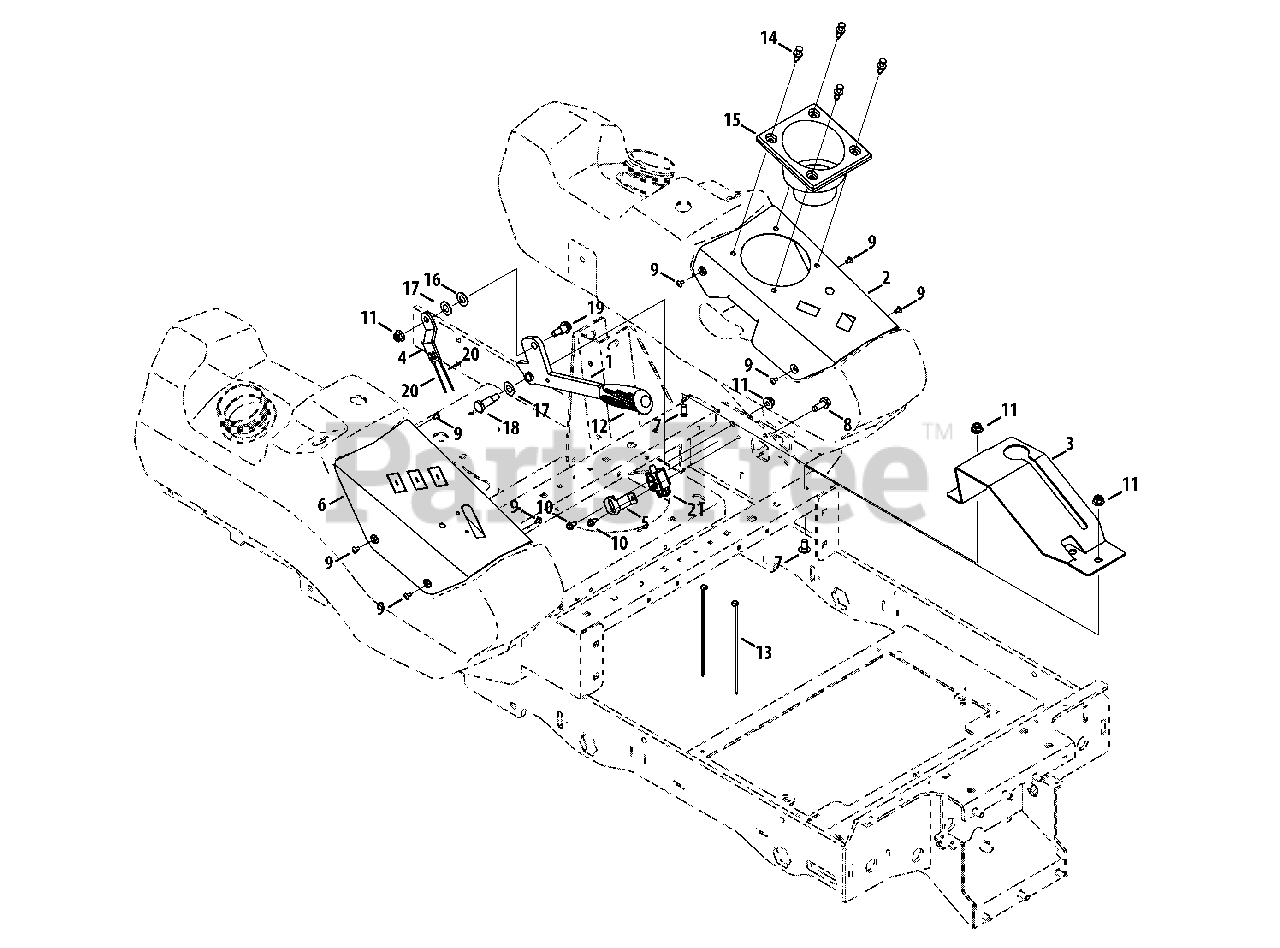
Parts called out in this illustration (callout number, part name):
1	Brake Handle Weldment
2	LH Control Panel
3	Boot Brake Bracket
4	Pivot Brake Bracket
5	Brake Switch Bracket
6	RH Control Panel
7	Carriage Bolt, 3/8-16 x .75
8	Screw, 3/8-16 x 1.00
9	Machine Screw, #10-32 x .25
10	Hex Flange Screw, 1/4-20 x .500
11	Nut, 3/8-16, Flangelock
12	Grip, .50 ID
13	Cable Tie
14	Rivet, .3125
15	Cup Holder
16	Washer, .510 x 1.00 x .060
17	Washer, .531 x 1.00 x .030
18	Shoulder Bolt, .50 x .925, 3/8-16
19	Shoulder Screw, .50 x .50, 3/8-16
20	Brake Cable
21	Switch, NC/NO/NO
